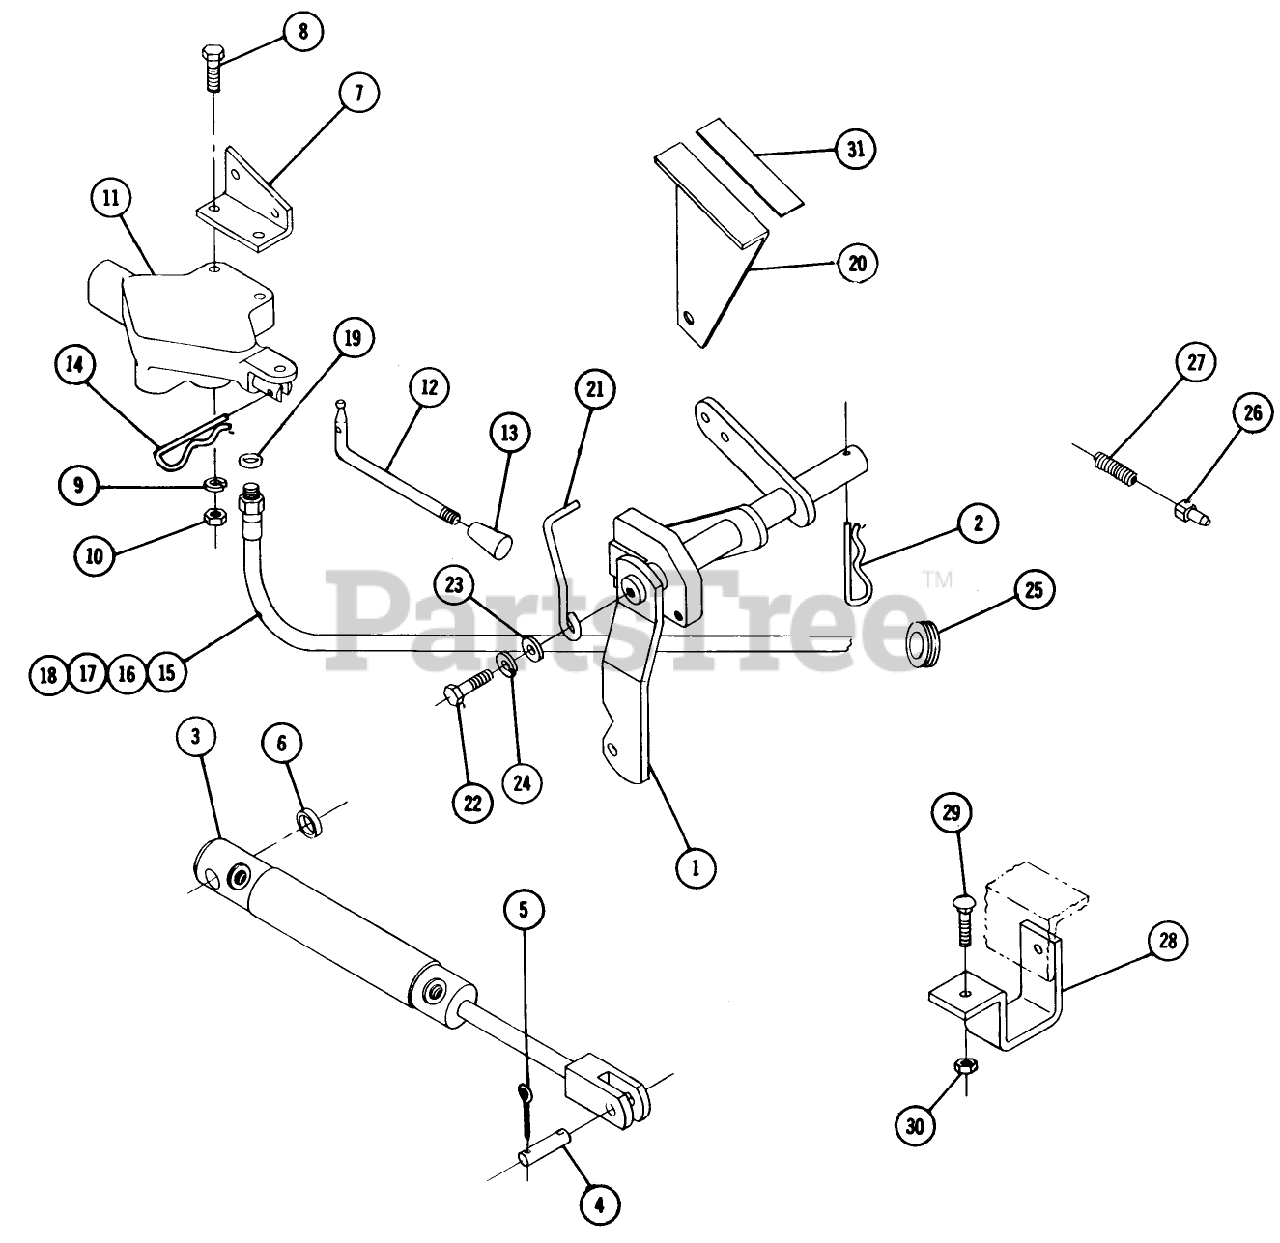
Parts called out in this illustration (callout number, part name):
2	Hairpen
5	Cotter Pin
8	Bolt 1/4 20 x 1 1/4
9	Lockwasher
10	Nut-Nylok
14	Hairpin
19	"O" Ring
21	Arm
22	Bolt 5/16-18 x
23	Washer
24	Lockwasher
28	Bracket
29	Bolt-Carriage 5/16-18
30	Nut 5/16-18
31	Decal
